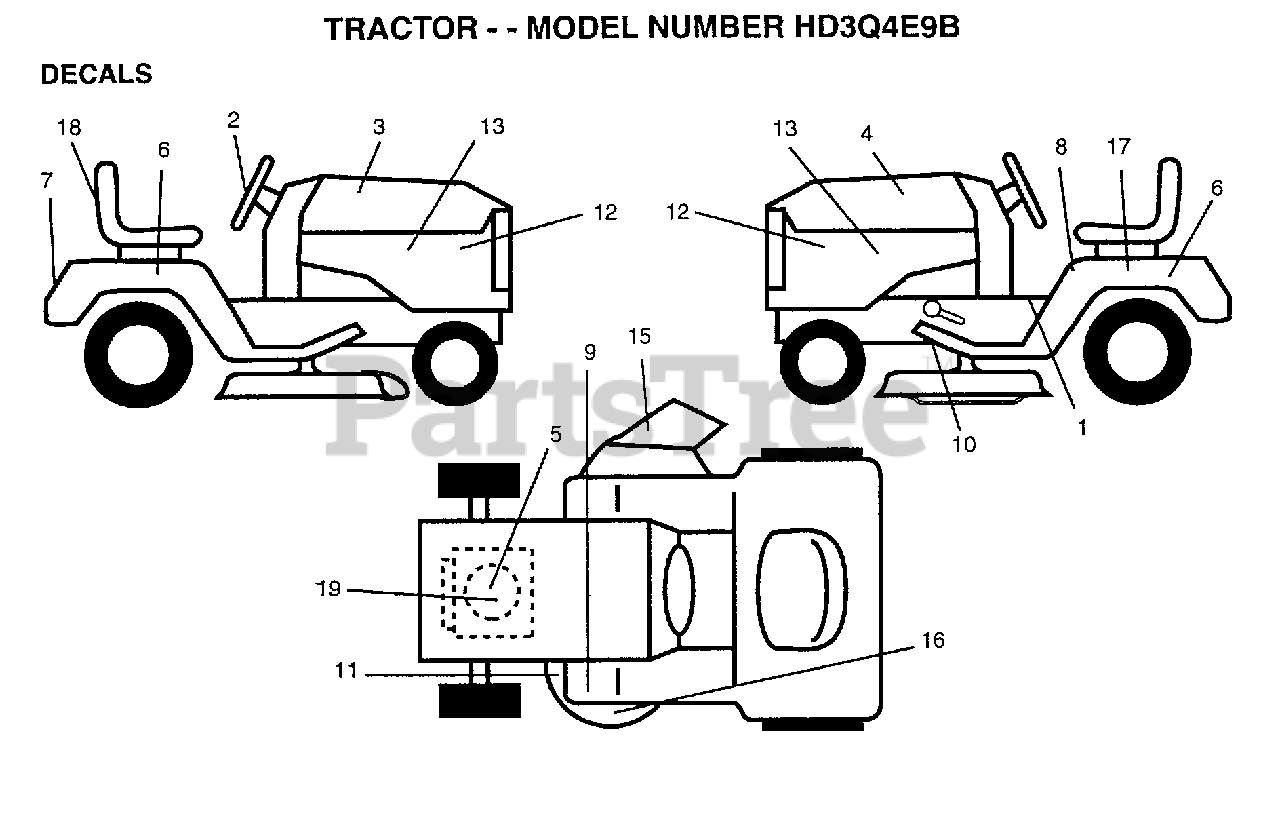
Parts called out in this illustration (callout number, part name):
1	DECAL.SADDLE.INST
2	DECAL.INST.WHL.ST
3	DECAL HOOD RH
4	DECAL HOOD LH
5	DECAL, HP, ENGINE
6	DECAL.FEND.QUICKS
7	DECAL.FENDER.HDEP
8	DECAL CAUT FEND
9	DECAL CLUT/BRAKE
10	DECAL.SCH.DRV.42
11	DECAL.SCH.PRIM.42
12	DECAL.PNL.SD.HDPO
13	GRASSBAG
15	"DECAL, WARNING"
16	DECAL.DECK.MULCH.
17	DECAL.BTRY.DANGER
18	DECAL SEAT ACC
19	DECAL.PART.18.5HP
